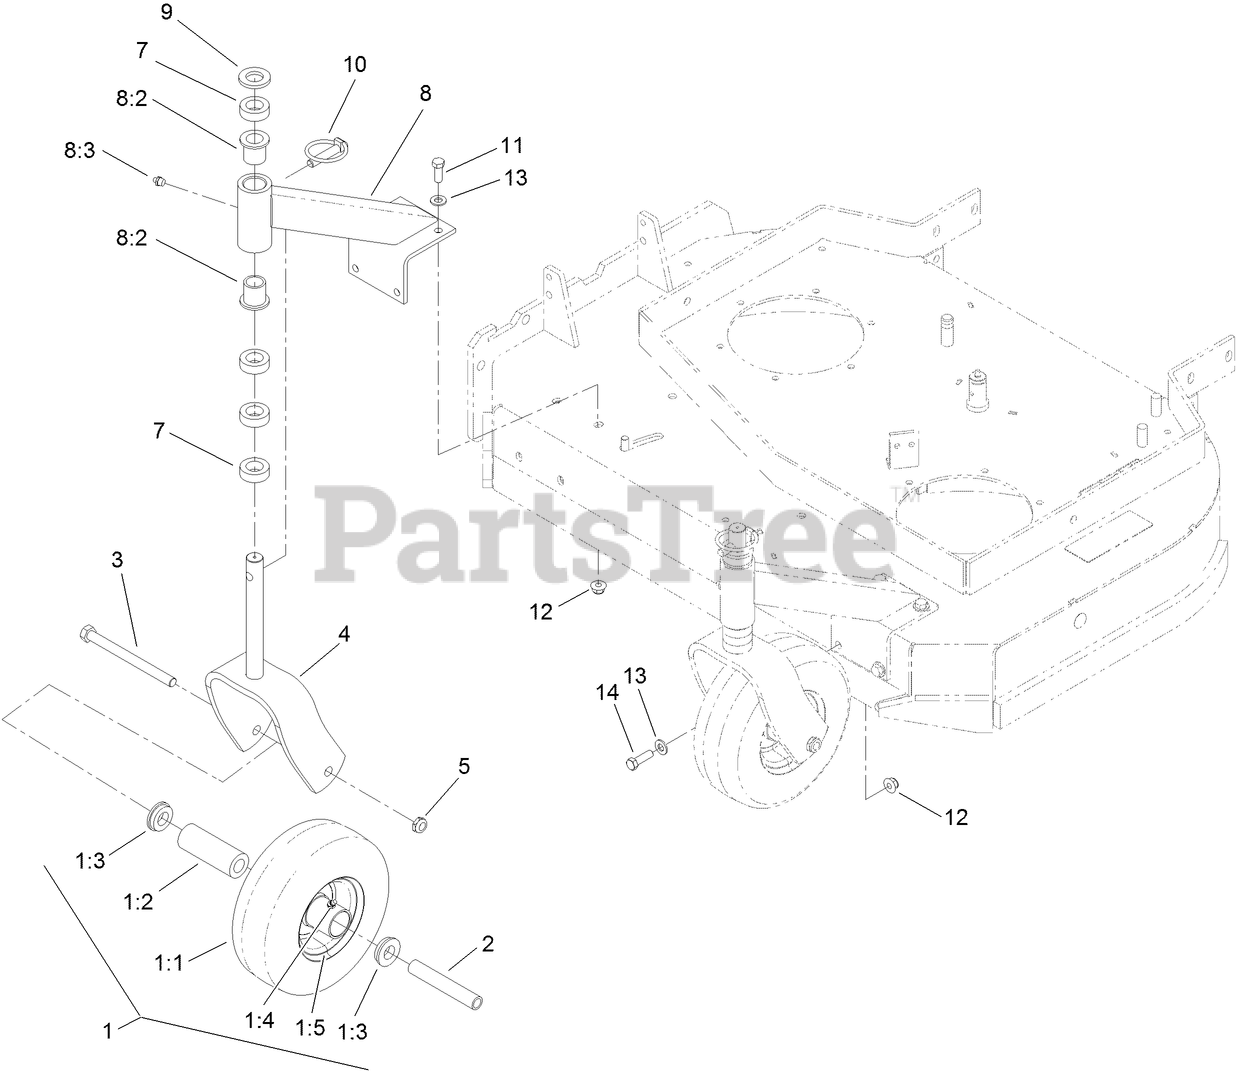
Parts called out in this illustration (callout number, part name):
1	WHEEL AND TIRE ASM
1:1	TIRE
1:2	BEARING
1:3	BUSHING
1:4	FITTING-GREASE
1:5	WHEEL
2	SPACER
3	SCREW-HH
4	FORK-CASTER
5	NUT-LOCK, NI
7	SPACER-CASTER
8	SUPPORT ASM
8:2	BEARING-FLANGED
8:3	FITTING-GREASE
9	WASHER-FLAT
11	SCREW-HH
12	NUT-HF, NI
13	WASHER-FLAT
14	SCREW-HH
